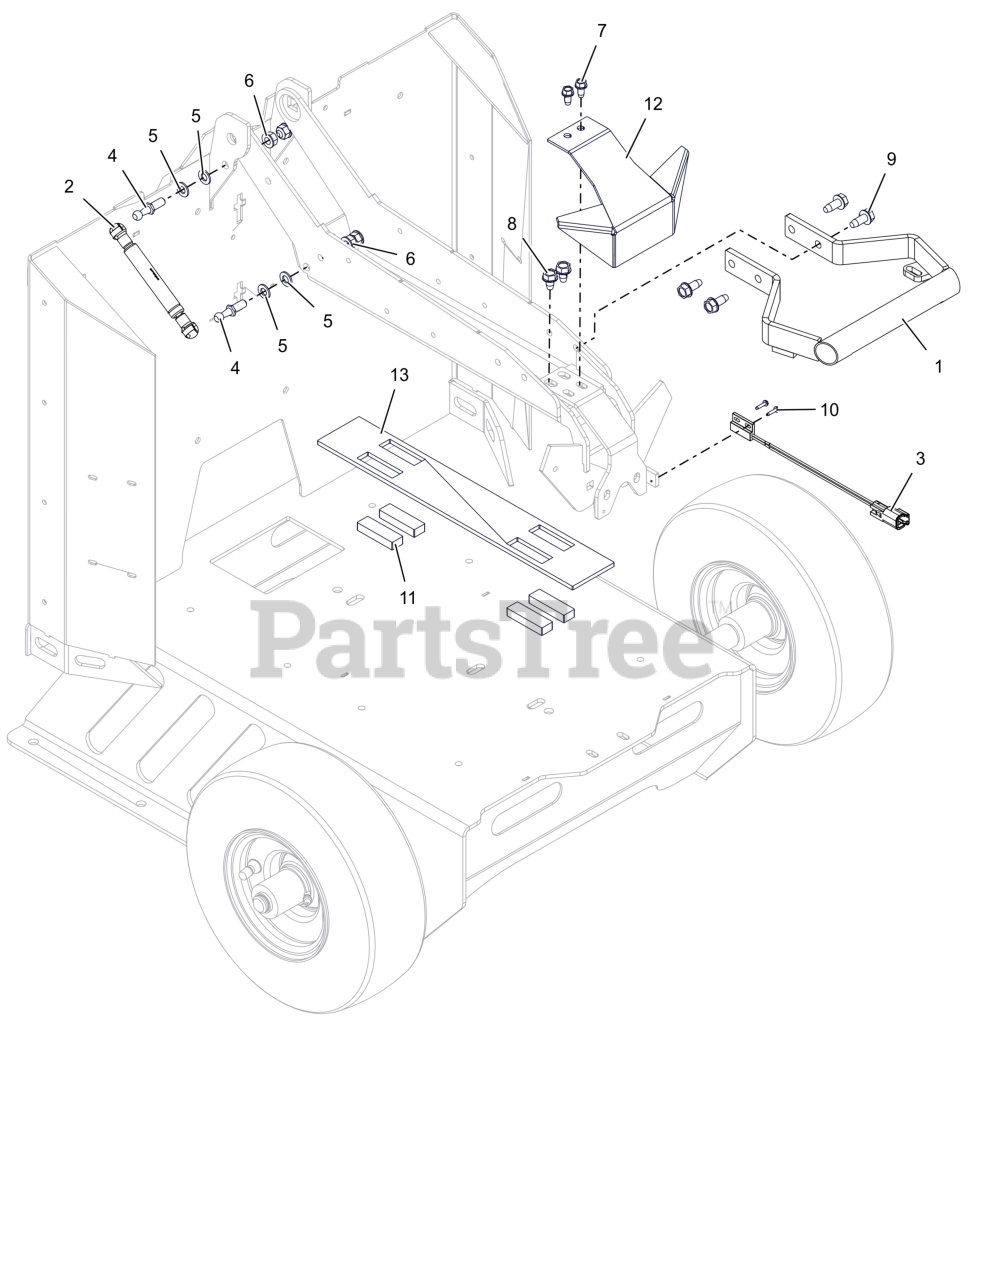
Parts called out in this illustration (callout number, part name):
1	WLDMT, HANDLE (BLUE)
2	DAMPER, GAS
3	SWITCH, MAGNETIC
4	STUD-BALL-THREADED
5	WSHR,FLT .323X.625X.062 ZCC
6	NUT,LK-CTR-FLG .31-18 GF ZCC
7	SCR-TAP .25-20X.50 HWH ZCC
8	SCR,TAP .312-18X.50 HWH TR ZCC
9	SCR,TAP .312-18X.75 HWH TR ZCC
10	SCR-TAP #4-40X.50 HWH ZCC
11	PAD, RUBBER
12	COVER, LATCH (BLUE)
13	PAD, RUBBER
